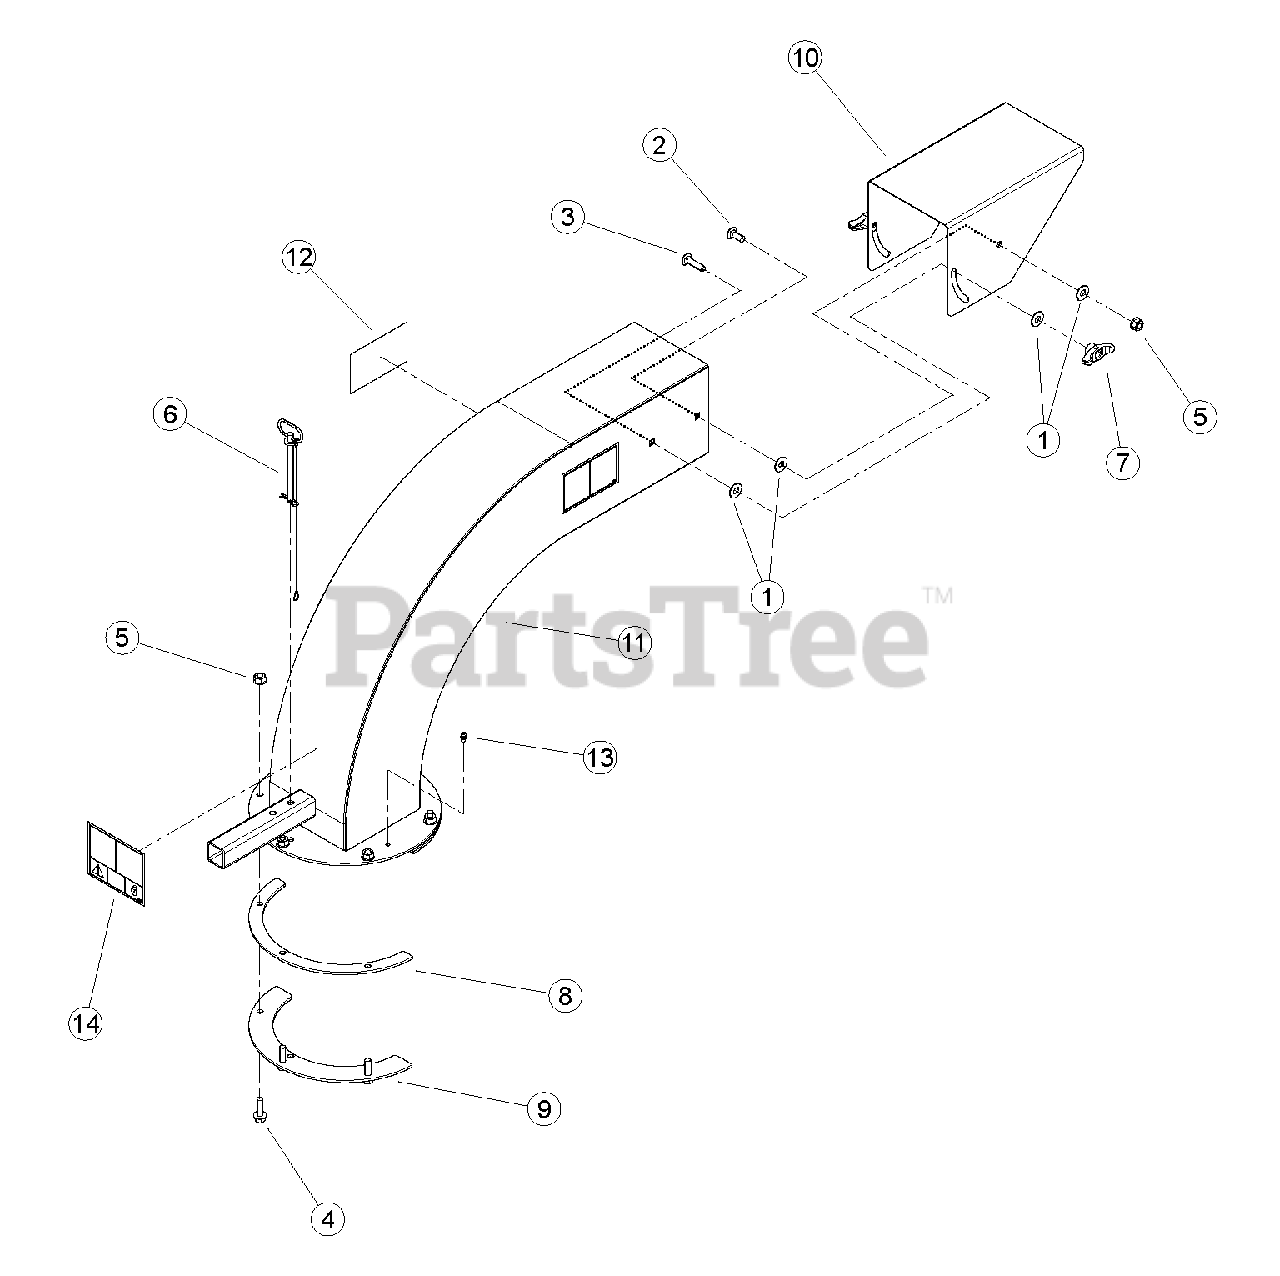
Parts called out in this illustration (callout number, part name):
1	WASHER, 3/8" FLAT ZP
2	BOLT, 3/8 X 1" GR5 CRG NC ZP
3	BOLT, 3/8 X 1-1/2"GR5 CRG NC ZP
4	BOLT, 3/8 X 1-1/4 FLANGE NC
5	NUT, 3/8-16 NYLOCK FLANGE
6	PIN, 3/8 X 4.25" DISCHARGE
7	KNOB, 3/8-16 UNC FEMALE TEE
8	RING, DISCHARGE SPACER
9	RING, DISCHARGE CLAMP
10	CAP, ORCHARD DISCHARGE
11	ASSEMBLY, ORCHARD DISCHARGE W/ DECALS
12	DECAL, DISCHARGE ISO
13	FITTING, 1/4 SELF-TAP GREASE
14	DECAL, DISCHARGE DEBRIS & LOCK
